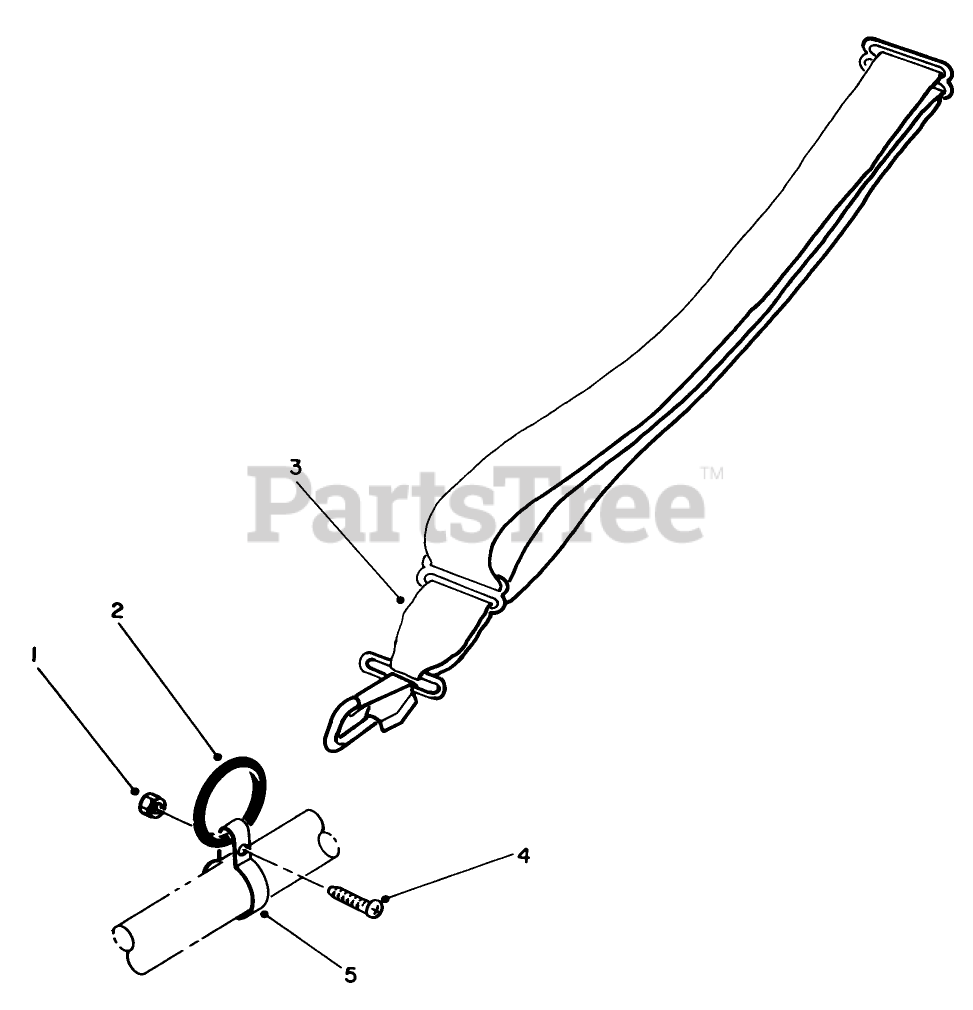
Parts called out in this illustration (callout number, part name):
1	Nut
2	Ring
5	Clamp
